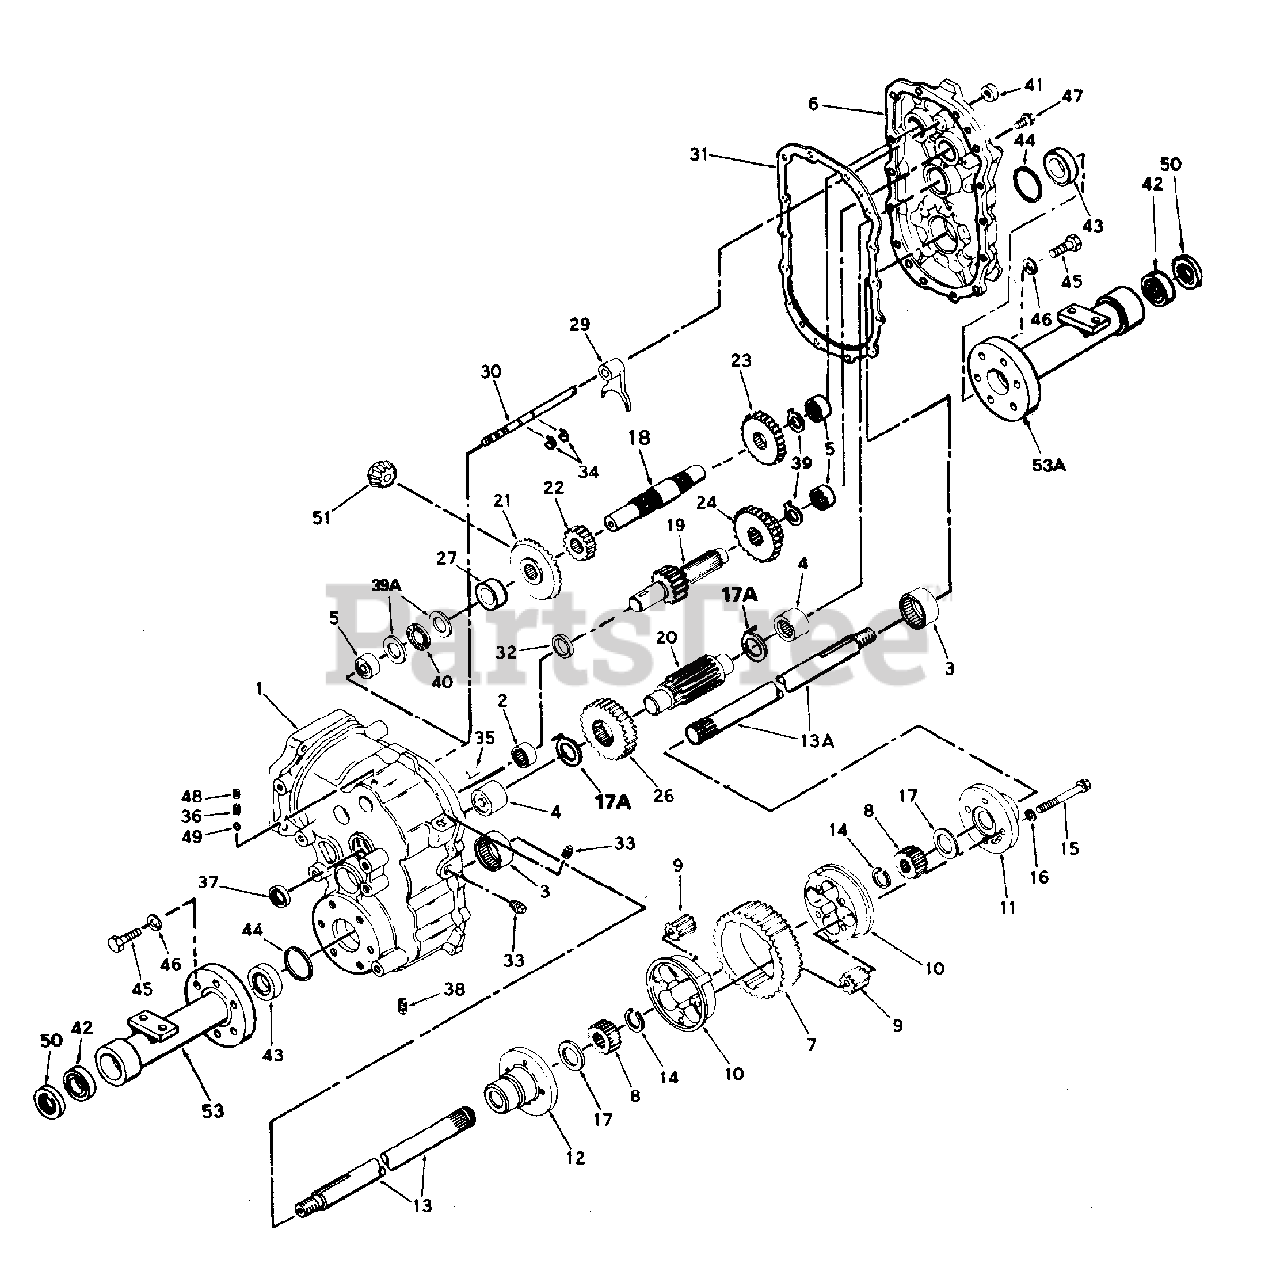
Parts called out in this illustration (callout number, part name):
1	Case Ass'y., Transaxle
2	Bearing, Needle
3	Bearing, Needle
4	Bearing, Needle
5	Bearing, Needle
6	Cover Ass'y., Transaxle
7	Gear, Ring
8	Gear, Side
9	Gear, Pinion
10	Core, Body
11	Carrier, Differential
12	Carrier, Differential
13	Axle, (18-17/64" Long)
13A	Axle, (15-29/64" Long)
14	Ring, Snap
15	Screw, Hex Hd. Mach.,3/8-16 x 3-3/8
16	Lock Washer, 3/8"
17	Washer, Thrust
17A	Washer, Thrust
18	Shaft, Counter
19	Shaft, Brake
20	Pinion, Output
21	Gear, Bevel (30 Teeth)
22	Gear, Spur (16 Teeth)
23	Gear, Spur (23 Teeth)
24	Gear, Cluster (20 and 27 Teeth)
26	Gear, Output (37 Teeth)
27	Spacer (55/64" Long)
29	Fork, Shift
30	Rod, Shift
31	Gasket, Case and Cover
32	Spacer
33	Plug, Pipe
34	Ring, Snap
35	Pin, Dowel
36	Spring
37	Seal, Oil
38	Plug, Magnetic Drain
39	Washer, Thrust
40	Bearing, Thrust
41	Seal, Oil
42	Bearing, Ball
43	Bearing, Thrust
44	Seal, Square Cut
45	Screw, Hex Hd. Mach.
46	Lock Washer, 1/2"
47	Screw, Hex Hd. Thd.Forming, 5/16-18 x 1
48	Screw, Set 1/4-20 x 1/2
49	Ball, Steel
50	Seal, Oil
51	Pinion, Bevel
53	Housing, Axle (9-1/4" Long)
53A	Housing, Axle (7-5/16" Long)
